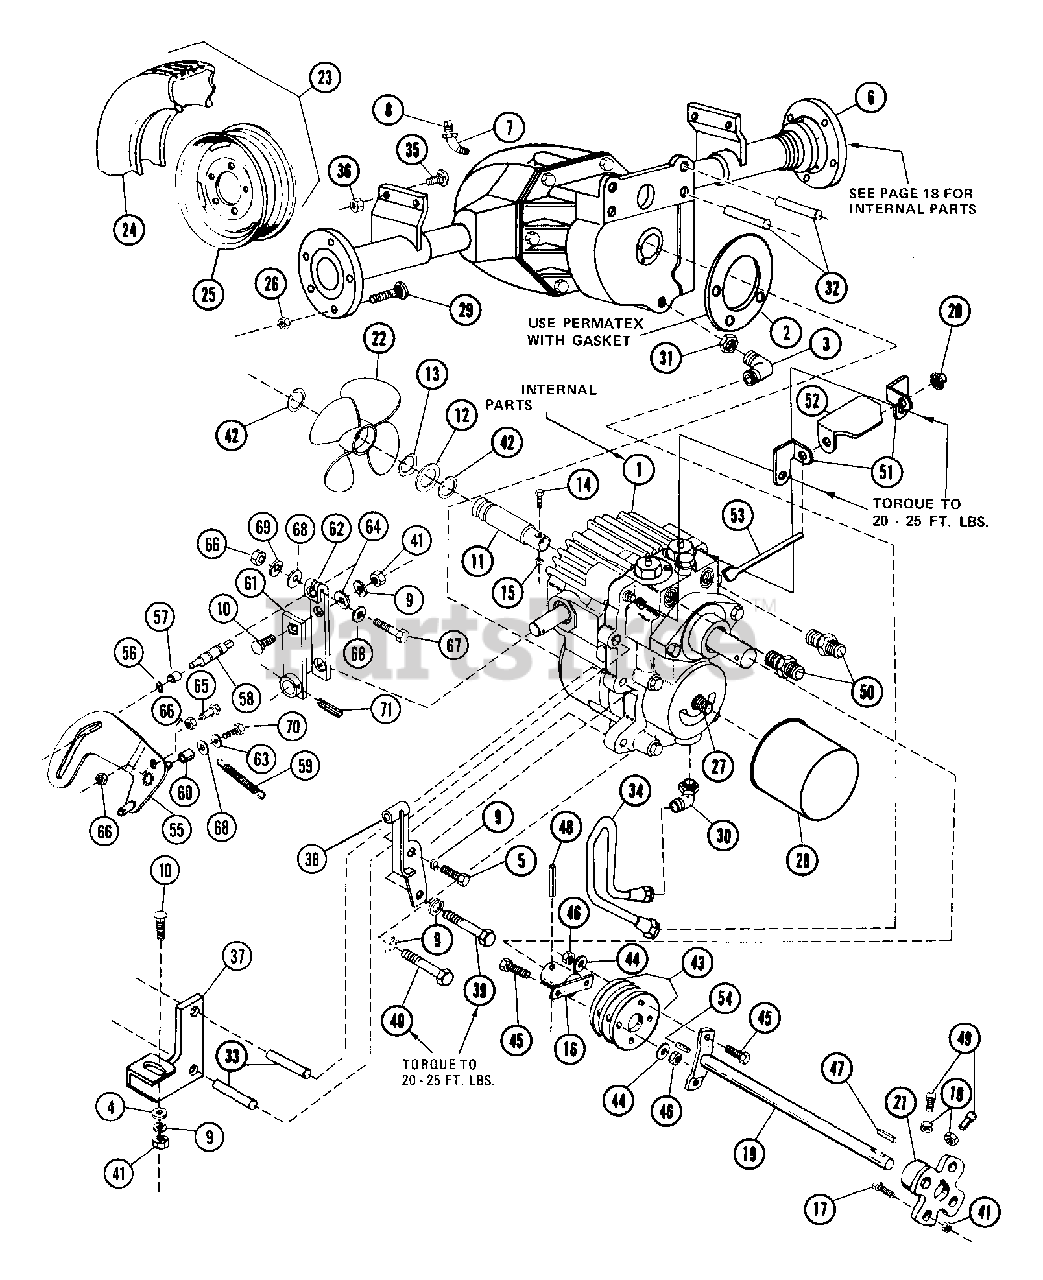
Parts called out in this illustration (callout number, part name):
1	12, 14, & 16 H.P. TRANSMISSION
1	12 H.P. TRANSMISSION ASSEMBLY
3	SWIVEL 90 DEGREE ELBOW
4	WSHR-FL-STL .438X1.0X.083 PL
5	BLT-HEX .38-16X1.50 PL GR2
6	AXLE & SUPPORTS
7	STREET ELBOW 1/2 X 45
8	PIPE PLUG
9	WSHR-LK .375X.094 MED PL
10	BLT-RDHDSQSHNK .38-16X1.00 PL
12	WSHR-FL-STL 1.016X1.625X.045
13	WAVE WASHER 1.015X1.50X.174
14	BLT-HEX .25-20X1.25 PL GR5
15	NUT-LK-CTR .250-20 PL
16	COUPLING
17	BLT-HEX .38-16X1.25 PL GR5
18	NUT-JAM .312-18 PL
19	DRIVE SHAFT ASSY
20	PUSH NUT, .312
21	HOUSING AND BUSHING ASSEMBLY
23	REAR TERRA TIRE 23X10.50X12
23	REAR TERRA TIRE
24	TIRE
25	WHL
25	WHL 12X8.50
26	NUT-LUG .437-20 YWZC
28	OIL FILTER
29	BLT-WHL-LUG .44-20X1.38 DANA
30	90 DEGREE ELBOW O RING
31	CONNECTOR
32	SPACER .379X.625X3.480
33	SPACER .379X.625X3.298
34	TUBE ASSEMBLY
35	BLT-RDHDSQNK .50-13X1.25 PL
36	NUT-LK .50-13 PL
37	BRACKET
38	CAM PIVOT BRACKET
39	BLT-HEX .38-16X5.00 PL GR2
40	BLT-HEX .38-16X4.75 PL GR2
41	NUT-HEX .375-16
42	RG-RTNG-EXT 1.00X.042
43	SPACER COUPLING
44	WSHR-FL-STL.344X.688X.065PL
45	BLT-HEX .31-18X1.25 PL GR2
46	NUT-LK .312-18 PL
47	KEY-WDRF .188X.75X.313 SAE 9
48	PIN-ROLL .250X1.25
49	SCR-SET .32-18X1.00 SKHCUP
50	CONNECTOR
51	SUPPORT
53	PIVOT ROD
54	PIN-ROLL .313X1.75
56	RG-RTNG-EXT .312X.025
57	CAM ROLLER
58	PIN ECCENTRIC
59	SG-TENS .060X.75X2.81 WLD 6
63	WSHR-FL-STL .531X1.062X.095 PL
64	WSHR-FL-STL.406X.812X.065PL
65	BLT-HEX .25-20X1.00 GR2
66	NUT-HEX .250-20 PL
67	BLT-HEX .25-20X2.00 PL GR5
68	WSHR-FL-STL.281X.62X.065 PL
69	WSHR-LK .250X.077 HVY PL
70	BLT-SERHFWH .25-20X.50 PL
71	PIN-ROLL .250X1.38
